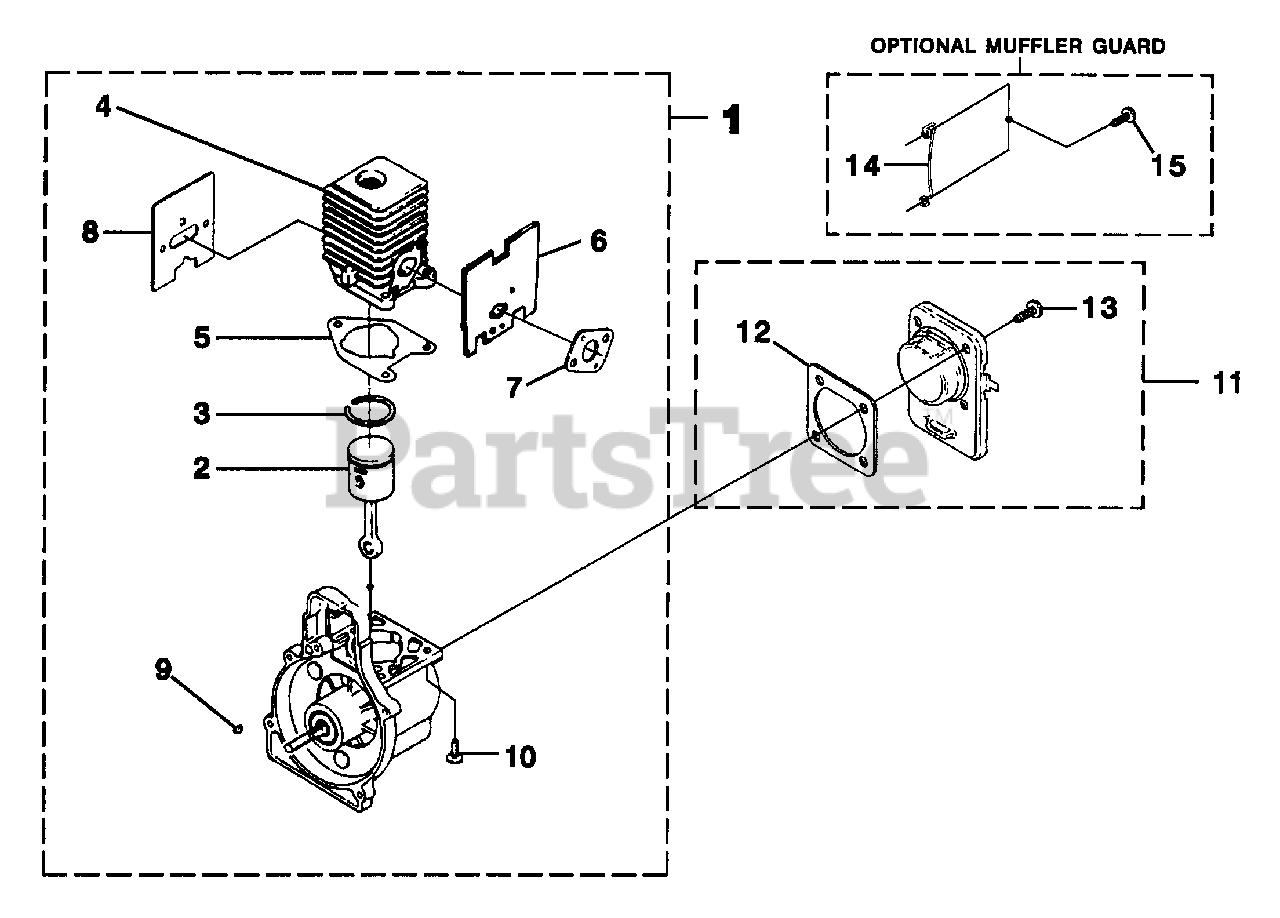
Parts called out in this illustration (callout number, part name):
1	SHORT BLOCK
2	PISTON & ROD ASSY.
3	RING-Piston
4	CYLINDER ASSY.
5	GASKET-Cylinder
6	GASKET-Heat Dam
7	GASKET-Carburetor
8	GASKET-Muffler
9	KEY-Woodruff
10	SCREW-Sems (12-24 X 3/4")
11	CRANKCASE COVER ASSEMBLY
12	GASKET-Crankcase Cover
13	SCREW-Sems (10-24 X 1/2")
14	MUFFLER GUARD
15	SCREW-Thread Forming (10-14 X 1/2")
